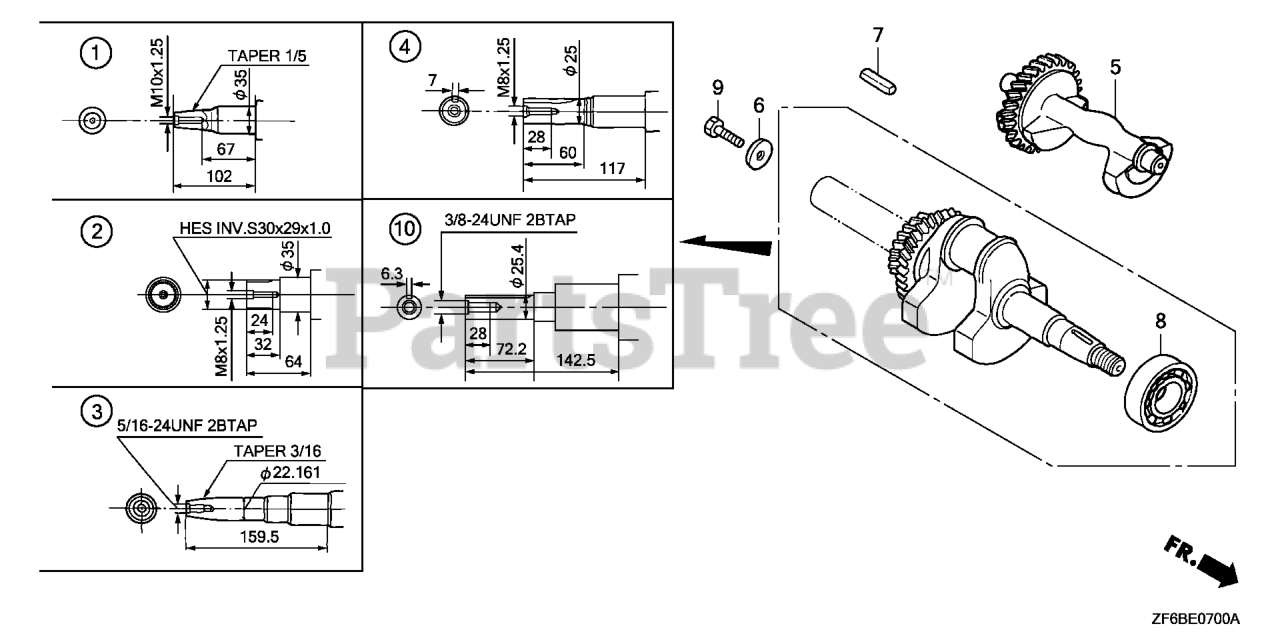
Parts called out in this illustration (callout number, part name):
5	WEIGHT, BALANCER
7	KEY (6.3X6.3X43)
8	BEARING, RADIAL BALL (6207SH)
10	CRANKSHAFT
